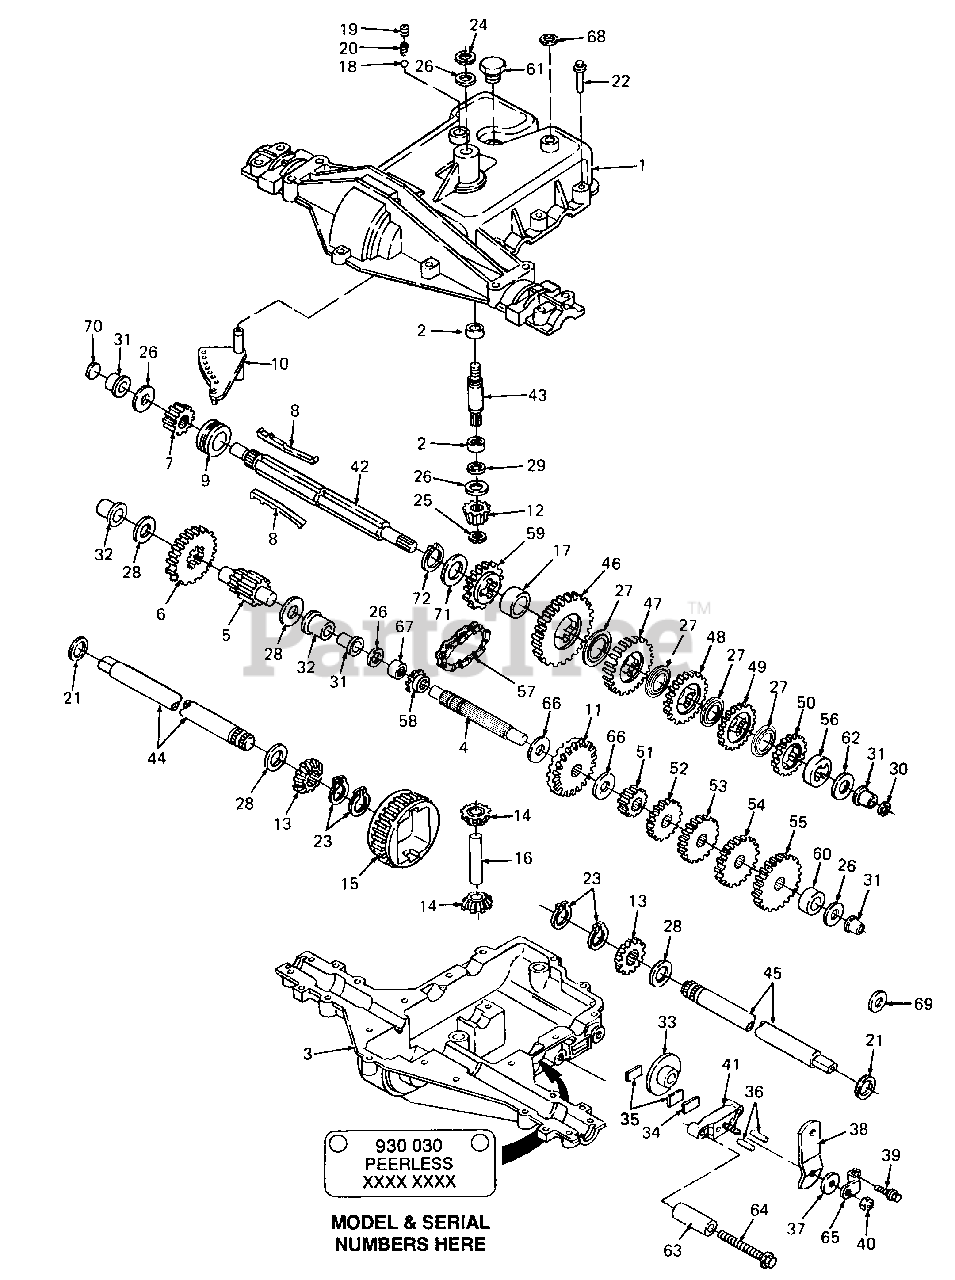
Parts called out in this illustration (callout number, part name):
1	Cover, Transaxle
2	Bearing, Needle
3	Case, Transaxle
4	Shaft, Counter
5	Shaft & Pinion Assy, Output
6	Gear, Output
7	Gear, Spur (15 Teeth)
8	Key, Shifter
9	Collar, Shifter
10	Rod & Fork Assy, Shift
11	Gear, Bevel (42 Teeth)
12	Gear, Bevel Input
13	Gear, Bevel
14	Gear, Bevel Pinion
15	Gear, Ring
16	Pin, Drive
18	Ball, 5/16 Dia, Grade 200
21	Ring, Seal
22	Screw, Flanged Hex, 1/4-20 X 1.25 Lg
23	Ring, Retainer (Set of 2)
24	Ring, Retaining
25	Ring, Ext Ret, .521
26	Washer, Thrust
29	Ring, Quad
30	Ring, Sq Cut
31	Bushing, Flanged
33	Brake, Disc
34	Plate, Brake Pad
35	Pad, Brake
36	Pin, Dowel
37	Washer Flat .344 X 1.0 X .063 HDN
38	Lever, Brake
39	Screw, Flanged Hex, 1/4-20 X 1.25 Lg
40	Nut
41	Holder, Brake Pad
42	Shaft, Brake (4-Keyed)
43	Shaft, Input
44	Axle, 11.62 Lg
45	Axle, 16.0 Lg
46	Gear, Spur (37 Teeth)
47	Gear, Spur (30 Teeth)
48	Gear, Spur (25 Teeth)
49	Gear, Spur (22 Teeth)
50	Gear, Spur (20 Teeth)
51	Gear, Spur (12 Teeth)
52	Gear, Spur (20 Teeth)
53	Gear, Spur (25 Teeth)
54	Gear, Spur (28 Teeth)
55	Gear, Spur (30 Teeth)
57	Chain, Roller
58	Sprocket (9 Teeth)
59	Sprocket (18 Teeth)
62	Washer, Thrust
64	Screw, Hex Flanged Hd, 1/4-20 X 2-1/4 Lg
65	Bracket, Brake Lever
66	Washer, Thrust
68	Seal, Sq Cut
70	Disk
71	Washer, Thrust
72	Ring, Retaining
